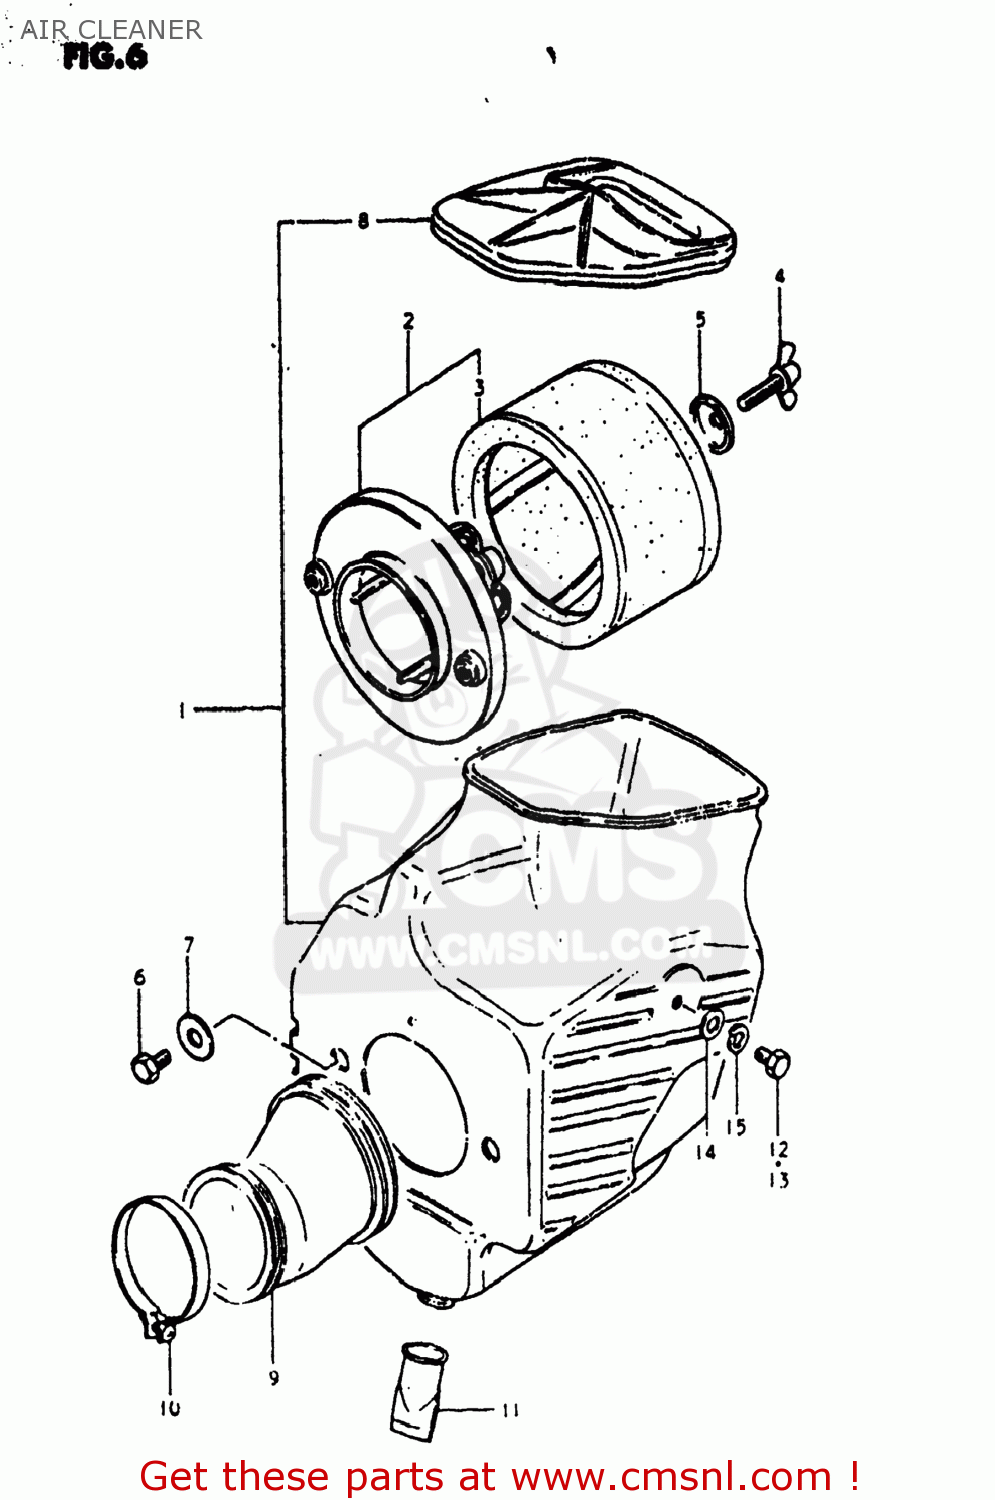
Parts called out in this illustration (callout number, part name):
1	CLEANER ASSEMBLY,AIR
2	FILTER ASSY
3	FILTER
4	WING BOLT,AIR CLEANER
5	HOLDER,FILTER
6	BOLT
7	SPACER,AIR CLEANER,REAR
8	CAP,AIR CLEANER
9	TUBE,AIR CLEANER OUTLET
10	CLAMP
11	HOSE,DRAIN
12	BOLT
13	SCREW
14	WASHER
15	LOCK WASHER
